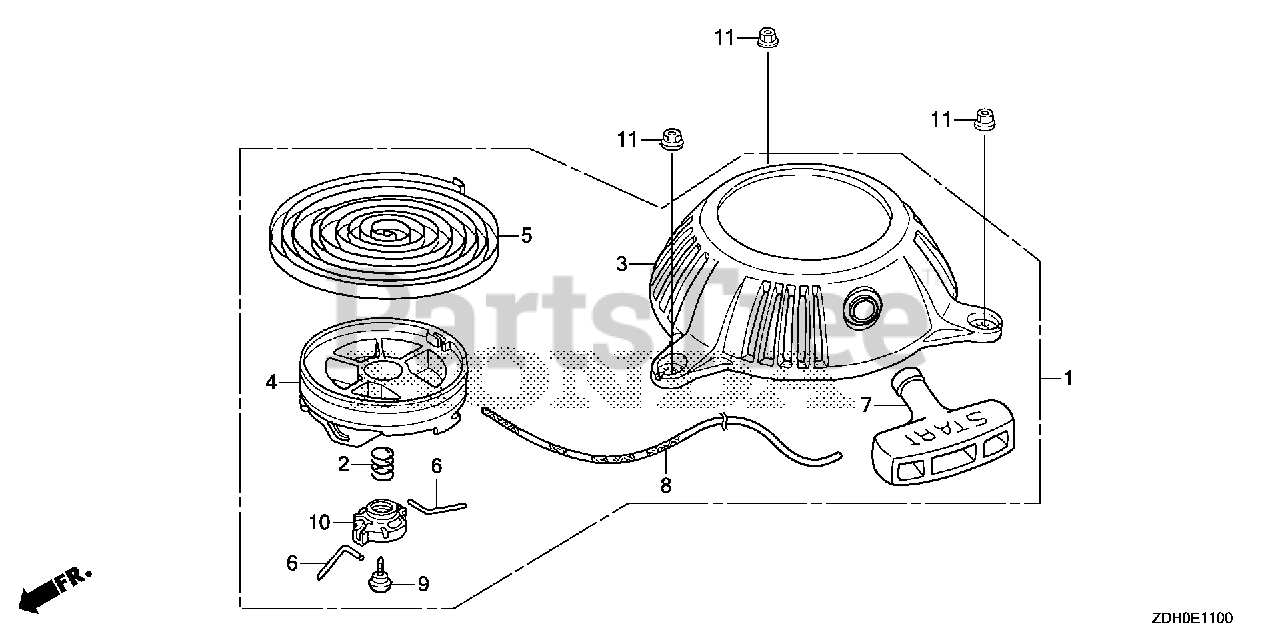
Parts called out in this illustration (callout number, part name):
1	STARTER ASSY., RECOIL
2	SPRING, FRICTION
3	CASE, STARTER
4	REEL, RECOIL STARTER
5	SPRING, RECOIL STARTER
7	GRIP, STARTER
8	ROPE, RECOIL STARTER
9	SCREW, SETTING
11	NUT, FLANGE (5MM)
